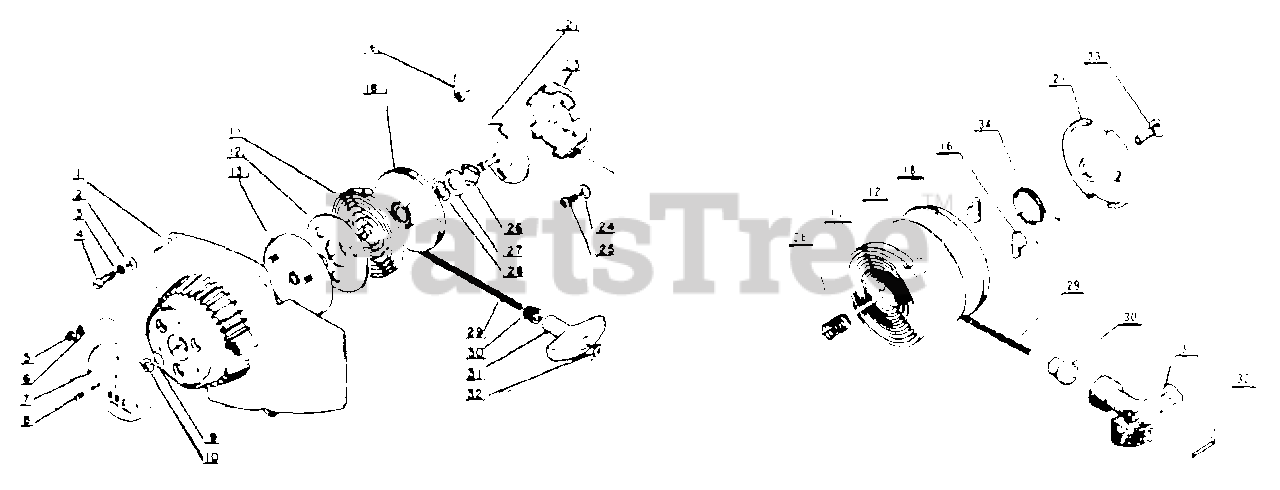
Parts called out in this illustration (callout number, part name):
1	CASE, STARTER
2	WASHER - 5
3	LOCKWASHER - 5
4	SCREW
5	NUT
6	Spring Water
7	NAME PLATE
8	SCREW
9	WASHER
10	RING, RETAINING
11	SPRING, REWIND
12	PLATE, SIDE
13	Spring retainer
16	PAWL, STARTER
18	PLATE, FRICTION
21	PLATE, FRICTION
23	CATCHER, PAWL
24	LOCKWASHER
25	BOLT
26	SPRING
27	WASHER
28	RING, RETAINING
29	ROPE, STARTER - 4X880
30	GUIDE, ROPE
31	GRIP, STARTER
32	WASHER
33	SCREW - SET
34	SPRING, RETURN
35	NUT - 5 -- CAP
